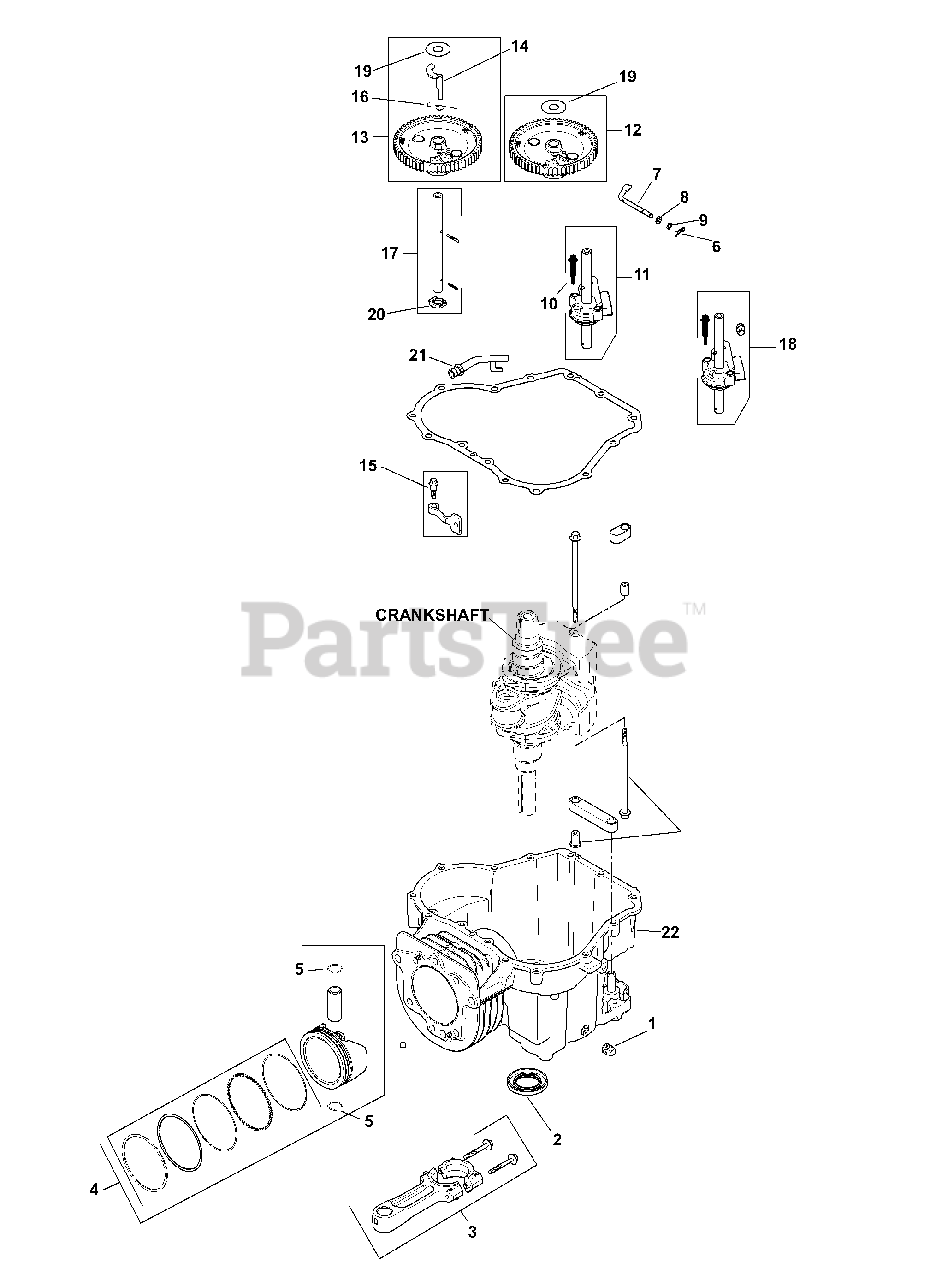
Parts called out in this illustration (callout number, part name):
1	Square Head Pipe Plug, 3/8
3	Connecting Assembly Rod
4	Piston W/ Ring Set Kit, 94mm
5	Piston Pin Retainer
6	Hitch Pin Clip
7	Governor Cross Shaft
8	Flat Washer, 6 Mm
9	Flat Washer, 1/4
10	Shd. Thd. Frm. Screw
11	Oil Pump Assembly Kit
12	Cam Lobe Assembly
13	Cam Gear Assembly
14	Acr. Weight and Follower Kit
15	Shd. Thd. Frm. Screw, M6 x 1 x 26
17	Cam Center Shaft Kit
18	Oil Pump Kit (Shallow 10mm)
19	Thrust -Acr. Washer
20	Thrust Washer
21	Drainback Tube
22	Crankcase
